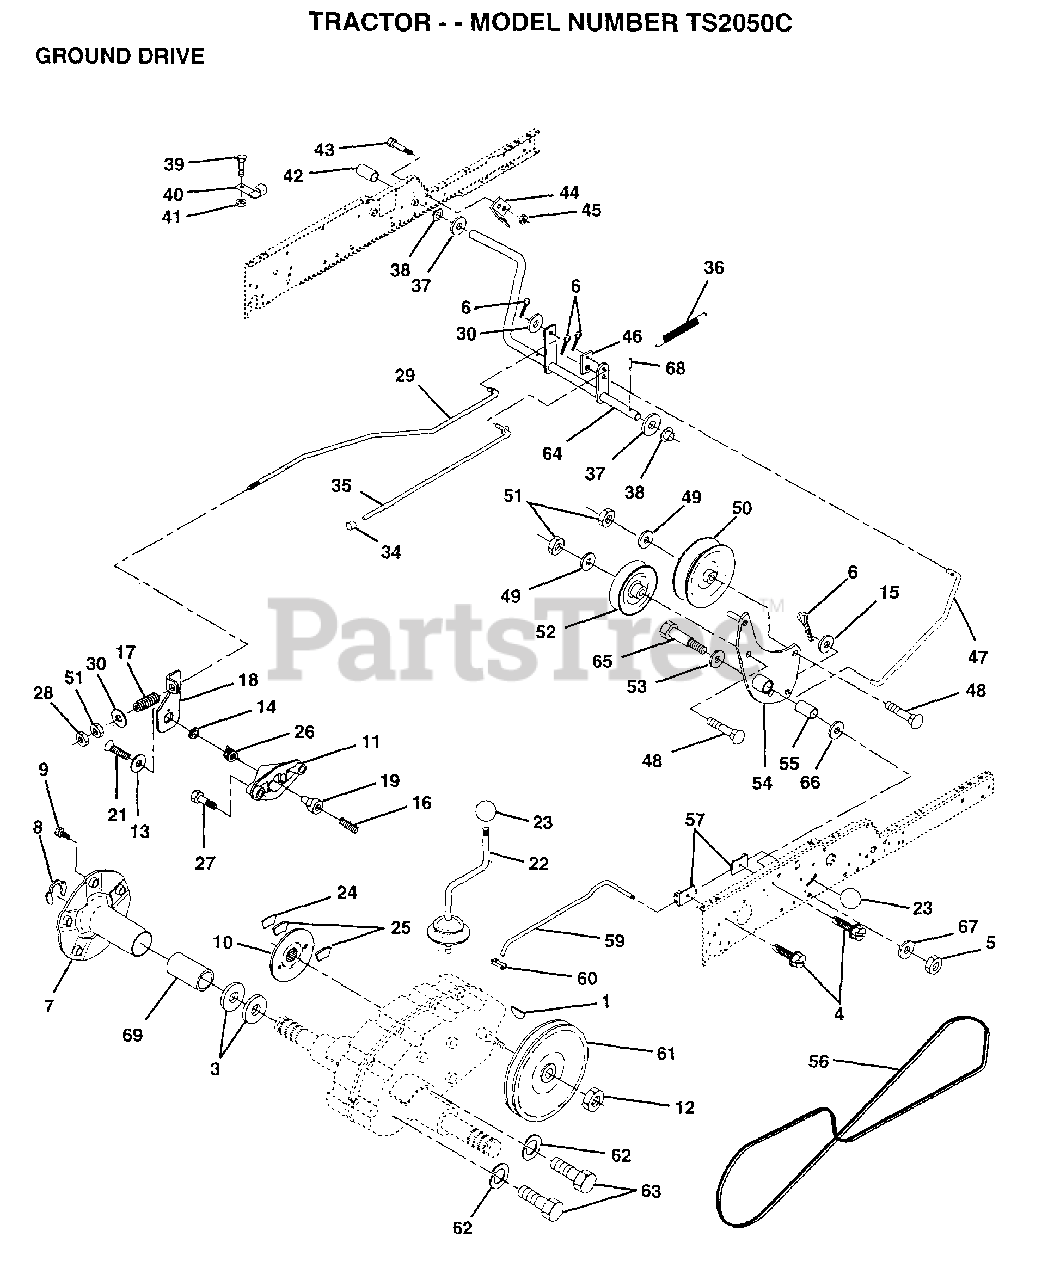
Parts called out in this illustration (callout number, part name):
3	WASHER T
4	SCREW LT
6	COTTER PIN
8	KLIP RING
9	BOLT.HUB.WHL.REAR
10	BRAKE.DISC.
11	YOKE BRAKE DISC
12	NUT STD
13	WASHER SPECIAL
14	BUSHING LEVER BKT
15	WASHER
16	SCREW SET 1/4-20
17	"SPRING,ROD BRAKE"
18	LEVER BRAKE GT
19	CAM BRAKE DISC GT
21	SCREW FLT 1/4X28
22	GEAR SHFT LVR T
23	KNOB
24	SUPPORT PUCK BRKE
25	PUCK BRAKE TOP
26	SPRING RET BRAKE
27	SCREW HX WASH
28	NUT
29	ROD BRAKE ZINC GT
30	WASHER HYT
34	PLUNGER CAP T
35	ROD BRAKE PART GT
36	SPRING.GRND.DRIVE
37	WASHER
38	BUSHING.NYLINER
39	SCREW
40	ACT-SWITCH T
42	PEDAL COVER T
43	BOLT LT
44	BRKT SWITCH GT
45	NUT
46	RETAINER.SPRING
47	ROD.CLUTCH
48	BOLT
49	WASHER
50	FLAT IDLER PULLEY
52	PULLEY.IDLER.V.GR
53	WASHER T
54	ARM.ASM.IDLER.CLU
55	"LY, BEARING"
56	BELTV.GR.DR.83.
57	BRACKET.ROD.SHIFT
59	ROD SHIFT HI LO
60	CONNECTING LINK
62	LOCKWASHER
63	BOLT
64	SHAFT-BRAKE/CLUTC
65	AXLE BOLT
66	WASHER.HARD.BLADE
67	WASHER
68	ROLL PIN STD
69	"COVER, HUB"
